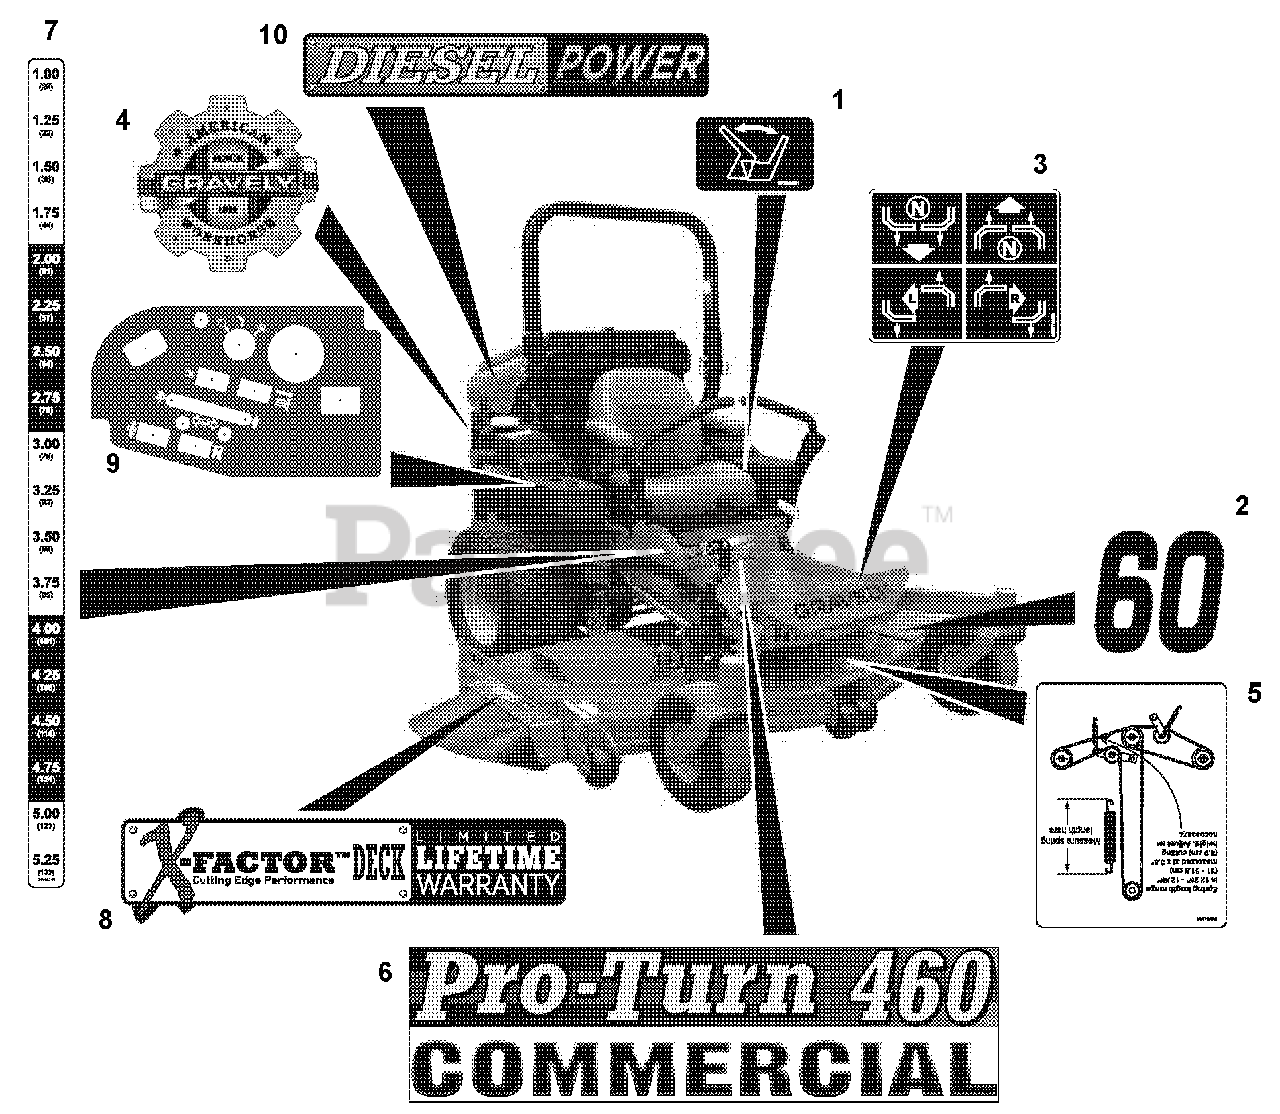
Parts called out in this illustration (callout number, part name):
1	Decal, Seat Release
2	Decal, 60 (992236)
3	Decal, Instructional Steering
4	Decal, Gravely Heritage
5	Decal, Belt Routing (992236)
6	Decal, Pro-Turn 460 (992236)
7	Decal, PT-400 Height of Cut
8	Decal, X-Factor Deck
9	Decal, Dash PT400 Diesel
10	Decal, Diesel Power
